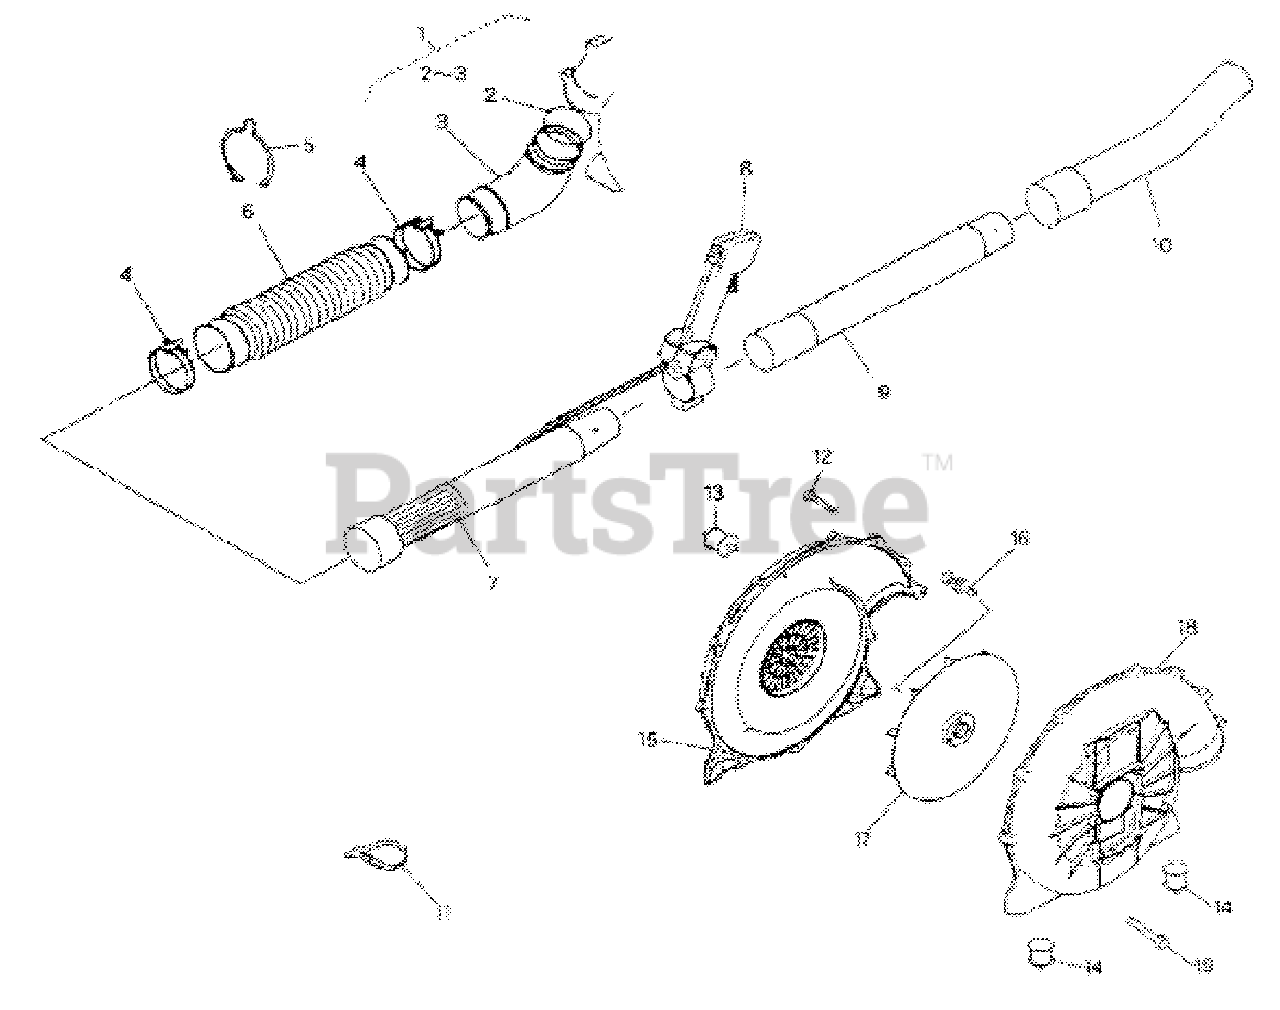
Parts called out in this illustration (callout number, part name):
1	Elbow Pipe
2	O-Ring
3	Elbow Pipe
4	Hose Band
5	Wire Clamp
6	Flex Pipe
7	Base Pipe
8	Throttle Assy.
9	Middle Pipe
10	Bend Pipe
11	Wire Band
12	Tapping Screw
13	Isolating Rubber
14	Isolating Rubber
16	Lock Bolt
19	Lock Bolt
